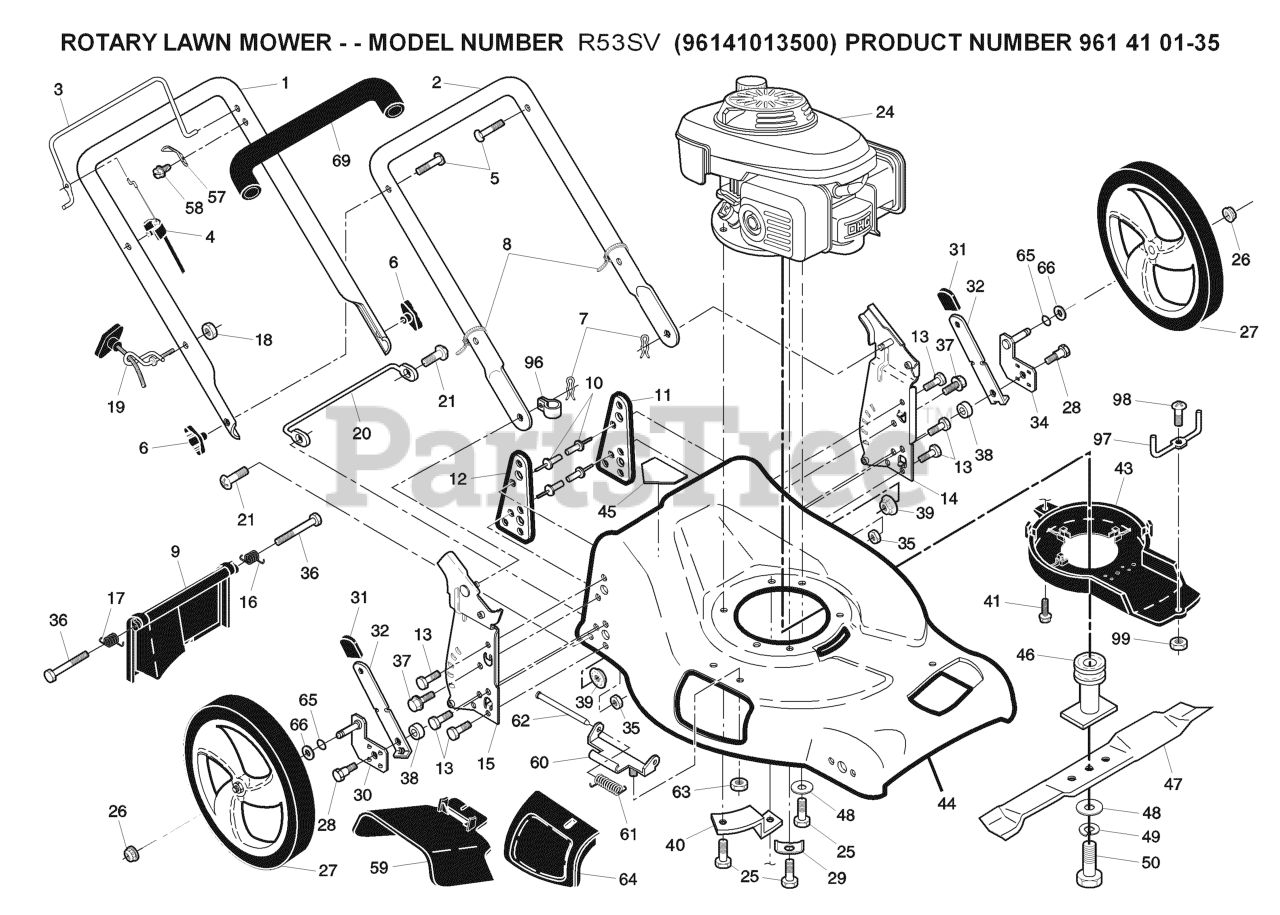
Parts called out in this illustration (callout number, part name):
1	RP HANDLE.ASM.UPPER.W/GRI
2	LOWER HANDLE
3	BAIL.DSTRT.FL.AW.CREAS.ORANGE
4	CABLE.ENGINE BRAKE.MZR
5	BOLT, HANDLE 5/16-18X1.75
6	KNOB, DEFLECTOR
7	HAIRPIN COTTER
8	TIE GUIDE
9	REAR DOOR ASSEMBLY
10	RIVET BLIND
11	SUPPORT BRACKET LH
12	BRACKET.SUPRT.RH.21.FWGD
13	SCREW 14-20 X 5/8
14	BRKT.ASM.HNDL.21FGD.EZ
15	BRKT.ASM.HNDL.21FGD
16	SPRING.REAR.DOOR.EZ.21.LT
17	SPRING.REAR.DOOR.EZ.21.RT
18	NUT
19	RB GUIDE.ROPE.STD.BLK.ZIN WSL
25	BOLT 3/8-16X1-1/8
26	NUT
28	SHOULDER BOLT
29	WASHER.ENGINE.BZP
30	ARM.ASM.AXLE.H/W,RR.BZ
31	SELECTOR KNOB
32	SPRING.SELECTOR.21.FWG.ZINC
33	NUT.71038.31-18.HEX.NYLOCK
34	ARM.ASM.AXLE.H/W.LR.BZ
35	NUT, HEX FLANGE 5/16-18
37	BOLT.FIN.HEX.5/16-18X3/4
38	WASHER.FLAT.34X1.38X22
40	BRACKET
41	SCREW.HEX.WSH
43	DEBRIS SHIELD
44	KIT.HSG.21.FGD.MC.ORG.CE SYM
45	DECAL.INTERNATIONL.CUTFINGER
46	Blade Adapter / Pulley
47	BLADE.21.PUSH
48	WASHER,HARDEN
49	LOCKWASHER
50	SCREW, HEX HD 3/8-24 X 1-3/8
57	BRACKET UPSTOP
59	DEFLECTOR.CLIPPIN.21.FGD
60	BRACKET.ASM.HINGE.21.FWGD.
61	SPRING.TORSION
62	ROD.HINGE.21
63	LOCKNUT.NYLOC.1/4-20
64	DOOR.MULCH.21.REAR.FWGD
65	O-RING..070X.487.NEOPRENE
66	WASHER.FLAT.1/2
69	GRIP.HANDLE.FOAM.WIDE.(1 SIDE)
96	CLIP.CABLE.BLK
97	KEEPER.BELT.FGD
98	SCREW.#8.MACH
99	NUT.HEX.#8
